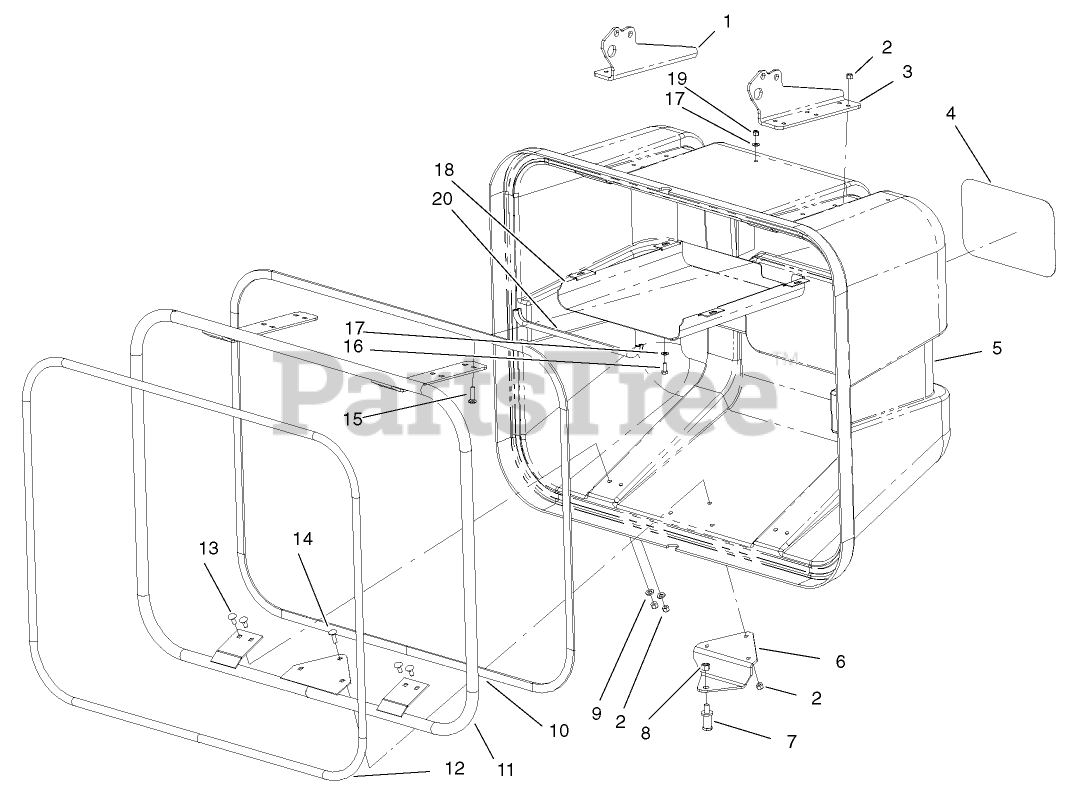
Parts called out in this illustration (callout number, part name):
1	RH HINGE ASM
2	NUT-LOCK, NI
3	LH HINGE ASM
4	DECAL
5	DOOR-200 SERIES
6	BRACKET-LATCH, DOOR
7	BOLT-STRIKER
8	NUT-LOCK, NI
9	WASHER-PLAIN
10	SEAL-HOPPER
11	LARGE DOOR FRAME ASM
12	SEAL-HOPPER, ROUND
13	BOLT-CARR
14	BOLT-CARR
15	SCREW-CARR
16	SCREW-HH
17	WASHER-FLAT
18	REAR SCREEN ASM
19	NUT-LOCK, NI
20	SEAL-TRIM
